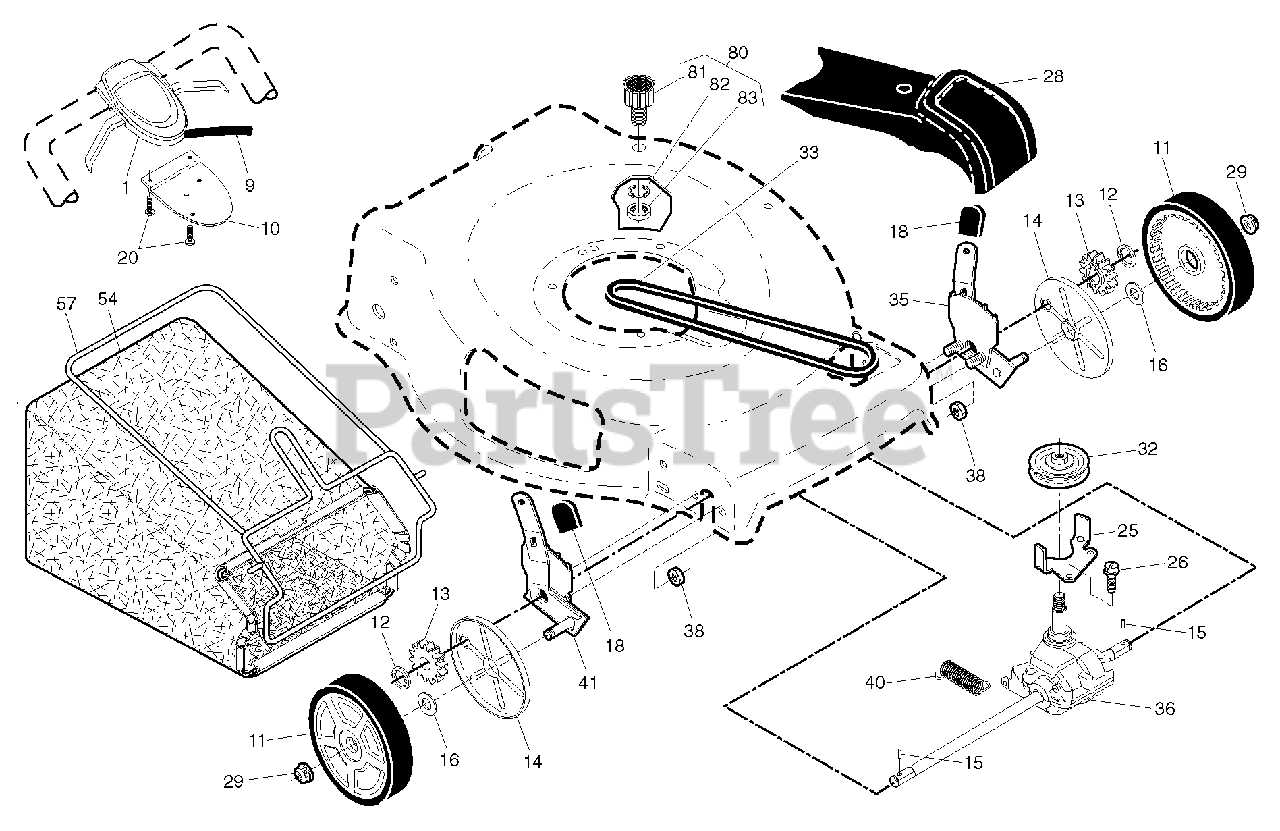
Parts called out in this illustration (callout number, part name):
1	CNTROL.AW22+FGD.ST.GEN.BLK/B
9	CABLE.CONTROL.22FGD.GEN2
10	BRACKET.DRIVE.CONTR.GEN2.BLACK
11	WHEEL.8X1.75.5SPK.RAD.YELLOW
12	E-RING 7/16 RE
13	PINION.14.TEETH.FGD
14	COVER.DUST.WHEEL.INNER.WALK
15	PAWL, DRIVE
16	WASHER FLUT
18	SELECTOR KNOB
20	SCREW, PHILLIPS HEAD 10 X 5/8
25	BRACKET.BELT.GUIDE.22+FGD.BZP
28	COVER.DR.ASM.22+FGD.GENERIC
29	NUT.HEX.FLANGE.3/8-16.LOCKNUT
32	PULLEY.DRIVEN.EZ/VARI (2 2MC)
33	BELT.DRIVE.FWD.
35	Adjuster Assembly Kit, LH Front
36	TRANSMISSION.22+.FWGD.SS
38	NUT.FLANGE.1-4-20-SERR
41	Adjuster Assembly Kit, RH Front
54	GBAG.A1640416S.BLK.PPRO.MRG.
57	Grass Bag Frame, 22+ Black
80	KIT.WASH-OUT.PORT
81	FITTING, HOSE, WATER WASHOUT
82	WASHER.LOCK.INTERNAL.TOOTH
83	LOCKNUT.HEX.WITH.O-RING
